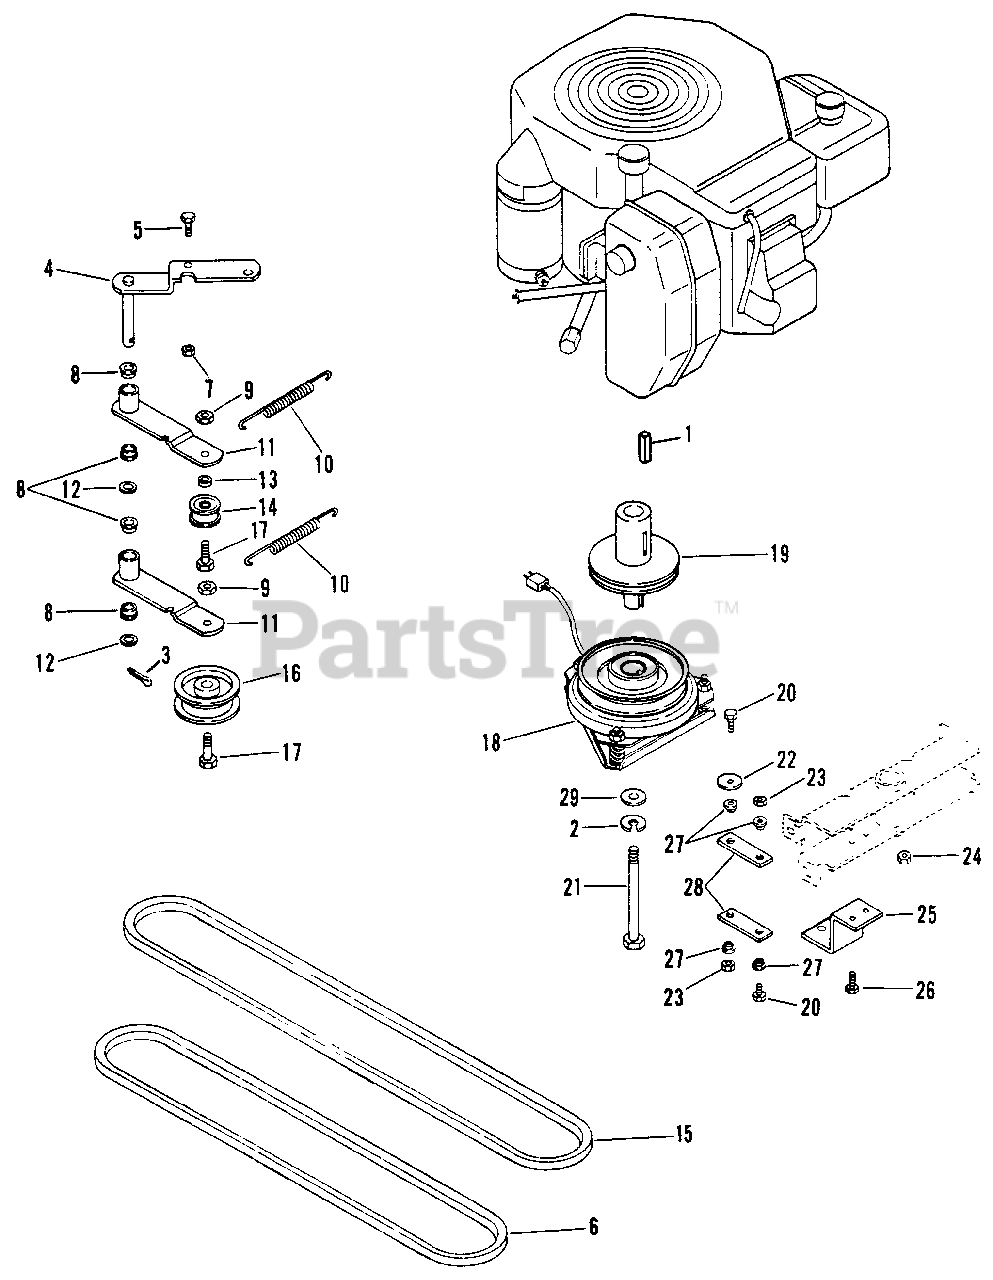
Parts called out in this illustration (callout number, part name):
1	Washer, Special
2	Washer, Lock 7/16 SP Heavy
3	Pin, Cotter .125 x 1.25
4	Weldment, Idler Pivot
5	Bolt, Hex 5/16-18 x .75
6	V-Belt, Jackshaft
7	Nut, Lock 5/16-18
8	Bushing, Flange
9	Nut, Lock 3/8-16
10	Extension Spring
11	Belt, Idler Arm
12	Washer, Flat .531 x 1.000 x .063
13	Bushing, .37 x .62 x .25
14	Idler
15	Belt, Transaxle
16	Idler
17	Bolt, Hex 3/8-16 x 1.50
18	Clutch, Electric
19	Shaft, Extension
20	Screw, Mach. 10-24 x 1.00 PHCR
21	Bolt, Hex M10-1.5 x 140 mm
22	Washer, Flat .265 x 1.250 x .063
23	Nut, Lock 10-24
24	Nut, Lock 1/4-20
25	Bracket, Torque
26	Bolt, Hex 1/4-20 x .750
27	Special Washer
28	Link
